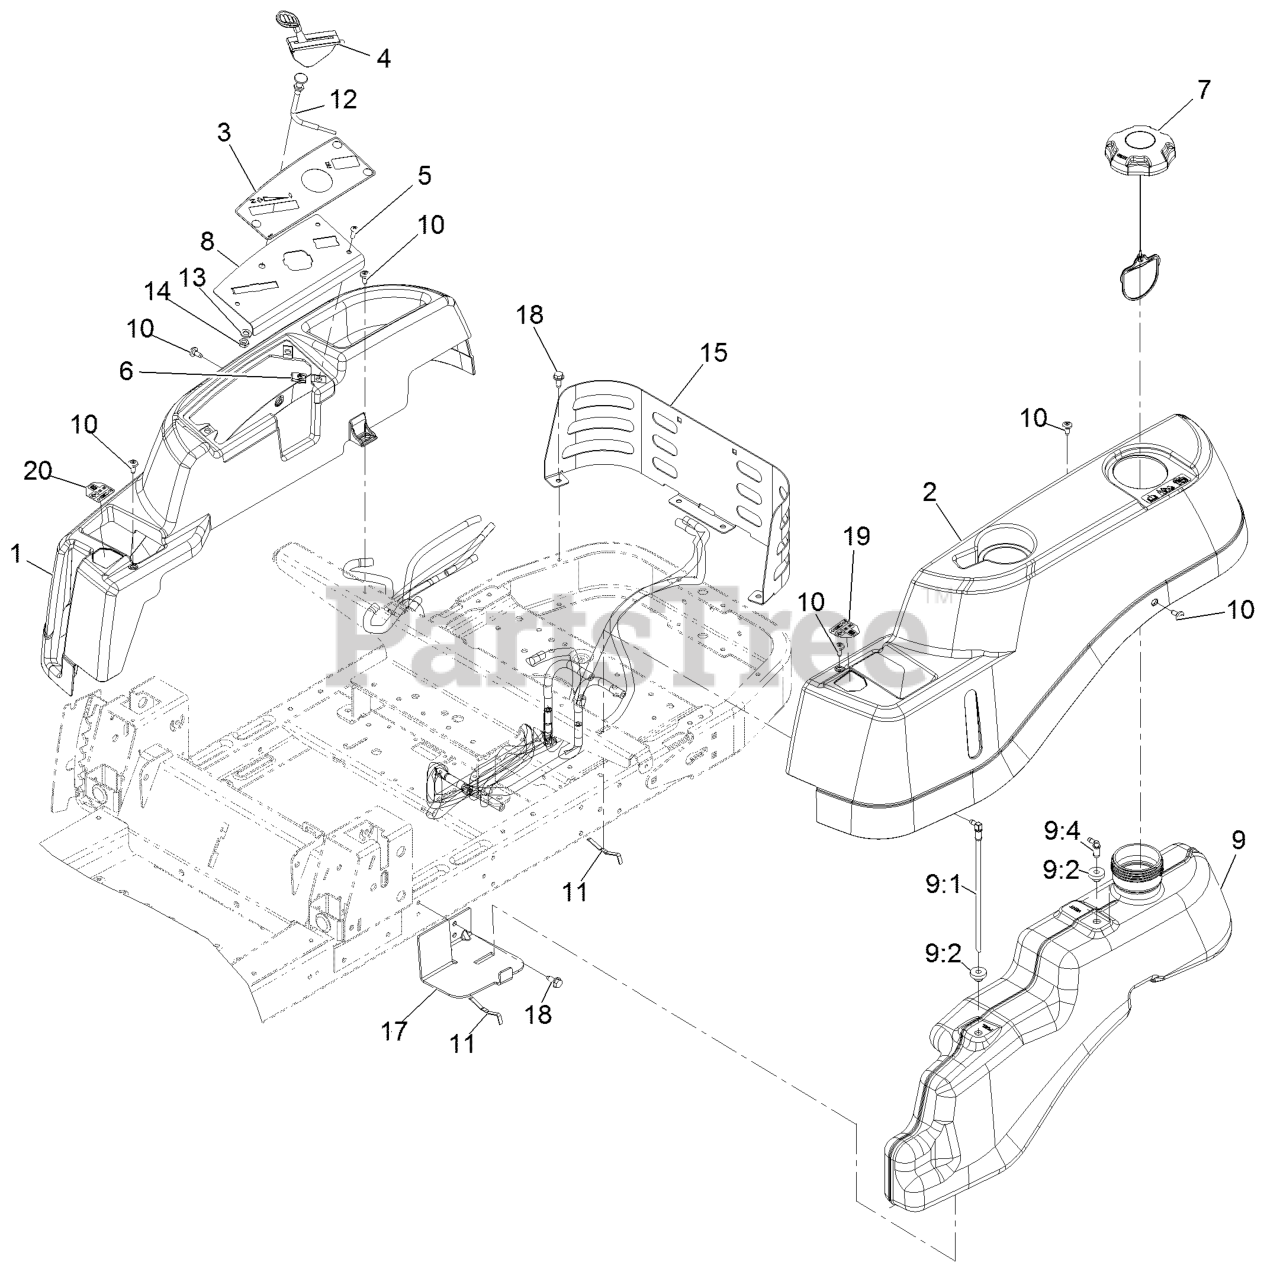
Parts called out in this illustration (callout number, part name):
3	DECAL-CONTROL PANEL
4	CABLE-THROTTLE
5	SCREW-PRH
6	Nut-Retainer-Panel 1/4-20
8	PLATE-CONTROL
9	FUEL TANK ASM
9:1	CONNECTOR-ELBOW, 90 DEG
9:2	BUSHING
9:4	FITTING-PLASTIC
10	SCREW-SHOULDER
11	SPRING
12	CABLE-CHOKE
13	WASHER-LOCK
14	NUT-HJ
15	GUARD-REAR, NARROW
17	SUPPORT-TANK, FRONT
18	Screw-HWH 5/16-18 X 3/4 Tf
19	DECAL-LEVER, CONTROL (LH)
20	DECAL-LEVER, CONTROL (RH)
